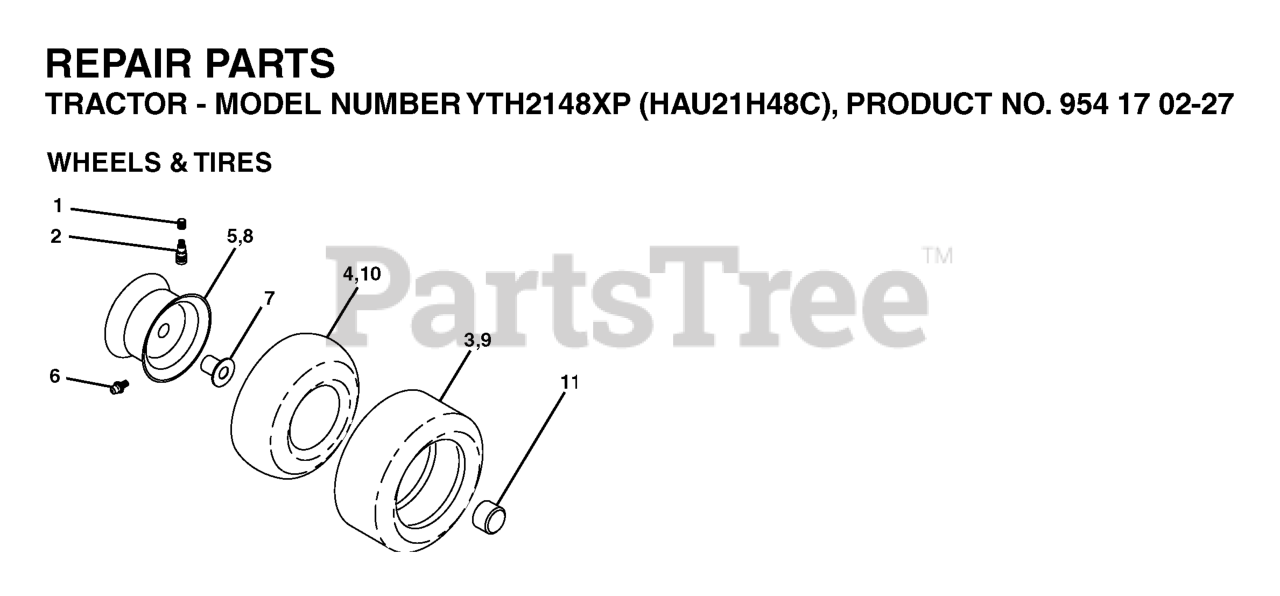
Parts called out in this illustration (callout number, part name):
2	VALVE STEM LT
3	TIRE HEAVY DUTY
4	TUBE.5.3/4.5/6
5	RIM ASM 6" FRONT SILVER
6	FITTING LT
7	BEARING T
8	RIM ASM 8" REAR SILVER
9	TIRE.TS.20X10-8
10	TUBE
11	CAP, AXLE BLK
